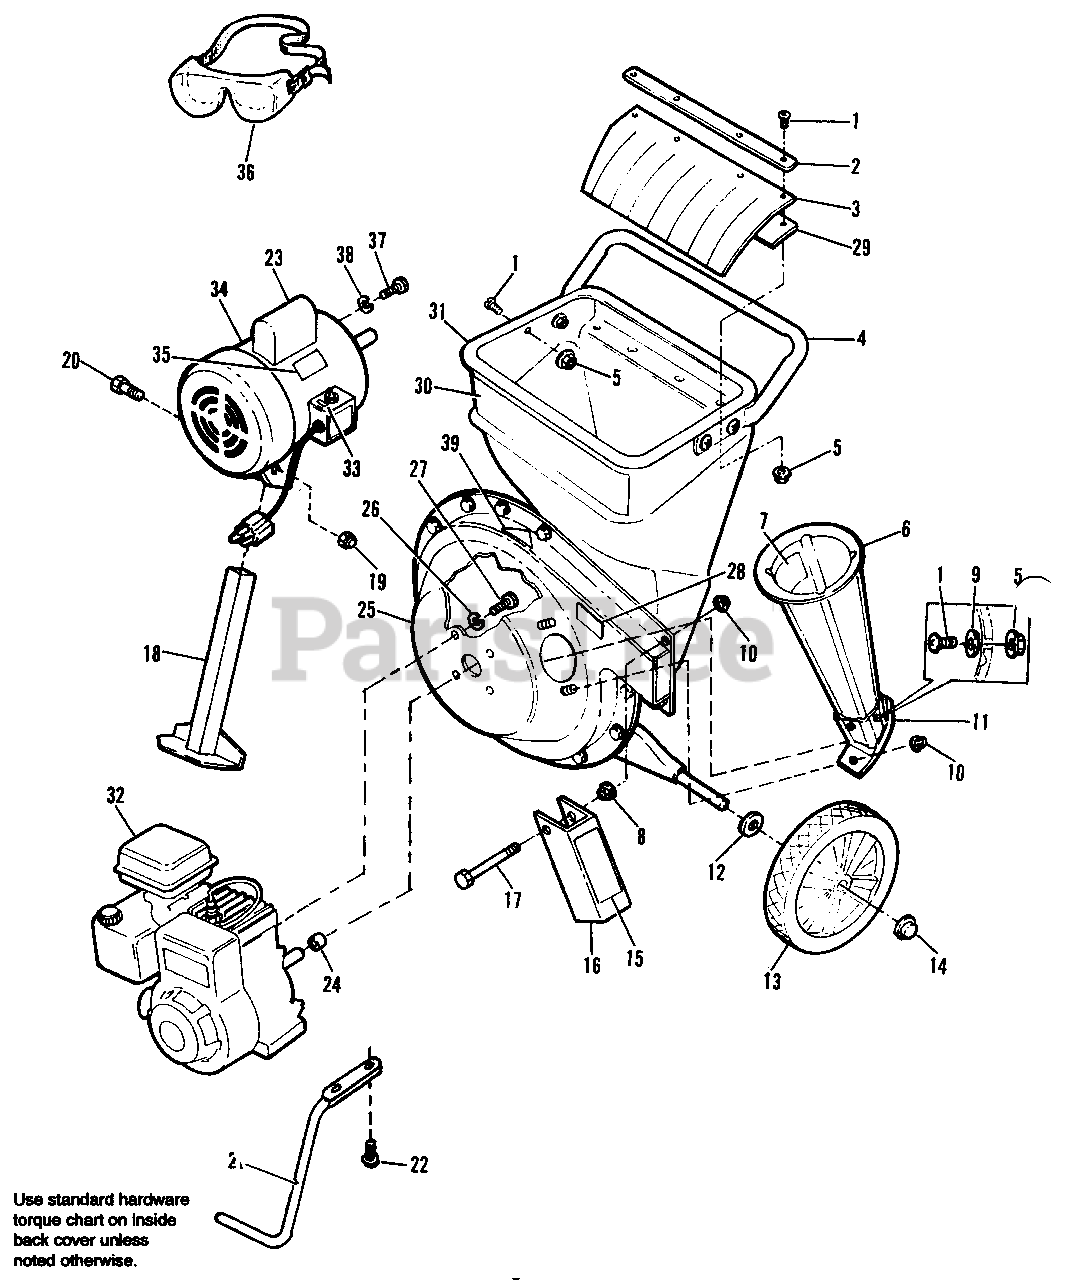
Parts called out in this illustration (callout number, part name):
1	SCREW, Hex, Button Hd., 1/4-20 x 3/4
2	RETAINING STRIP, Hopper Guard
3	GUARD, Hopper
4	HANDLE, Hopper
5	NUT, Flange, 2-Way, 1/4-20
6	CHIPPER CONE (Orange)
6	CHIP CONE (Gold)
6	CHIPPER CONE (Red)
7	DECAL, Danger
8	NUT, Shoulder
9	WASHER, 1/4
10	NUT, Whiz, 5/16-18
11	BLOCK, Chipper Cone
12	WASHER, 1/2
13	WHEEL & TIRE ASSY., 1-3/4 x 12
14	PUSH NUT, 1/2
15	DECAL, Danger (Narrow)
16	DISCHARGE DEFLECTOR
17	BOLT, Shoulder
18	LEG TUBE ASSY. (2/10 Only)
19	NUT, ESNA, 5/16-18 (2/10 Only)
20	CAPSCREW, Hex. Hd., 5/16-18 x 1-3/4 (2/10 Only)
21	LEG TUBE ASSY., (3/10, 5/10 Only)
22	SCREW, Hex, Taptite 3/8 16 x 1-1/4 (3/10, 5/10 Only)
23	ELECTRIC MOTOR ASSY., 1-1/2 HP (2/10 Only)
24	SPACER (3/10, 5/10 Only)
25	CHIPPER HOUSING (2/10 Only)
26	LOCKWASHER, 5/16 (3/10, 5/10 Only)
27	CAPSCREW, Hex Hd., 5/16-24 x 3/4 (3/10, 5/10 Only)
28	I.D. PLATE
29	SUPPORT, Hopper Guard
30	DECAL, 2/10 Simplicity
30	DECAL, 3/10 Simplicity
30	DECAL, 5/10 Simplicity
30	DECAL, 2/10 Baker
30	DECAL, 3/10 Baker
30	DECAL, 5/10 Baker
31	SHREDDER HOPPER, (Orange)
31	SHREDDER HOPPER, (Gold)
31	SHREDDER HOPPER, (Red)
33	DECAL, On-Off (2/10 Only)
34	DECAL, Danger-Motor (2/10 Only)
35	DECAL, Caution-Motor (2/10 Only)
37	CAPSCREW, Hex Hd., 3/8 16 x 5/8 (2/10 Only)
38	LOCKWASHER, 3/8 (2/10 Only)
39	DECAL, OPEI
